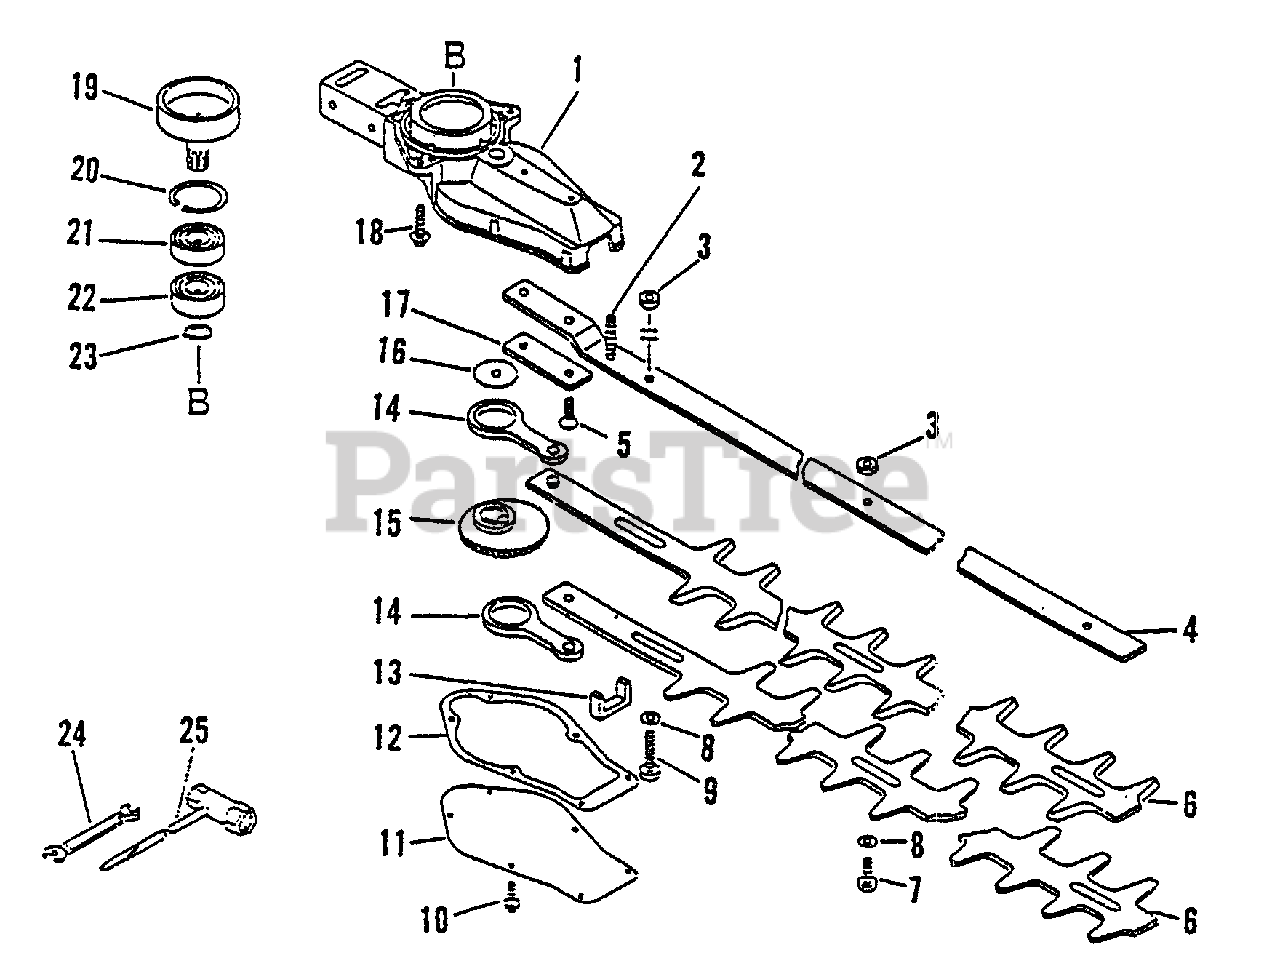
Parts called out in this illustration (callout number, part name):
1	CASE, GEAR
2	SCREW 5×30
3	NUT, LOCK 6
4	BAR, FRAME
5	SCREW 6×18
7	BOLT, CUTTER
8	WASHER 6.5×15.5×0.6
9	BOLT 6×35
10	SCREW 4×10
11	LID, GEAR CASE
12	GASKET, GEAR CASE
14	ROD, CONNECTING
17	PLATE, EYE
18	SCREW 5×20
19	DRUM, CLUTCH
20	RING, SNAP 35
21	BEARING, BALL 6202
22	BEARING, BALL 6202
23	RING, SNAP 14
24	WRENCH, W/SCREWDRIVER
25	SPANNER - 8×10
